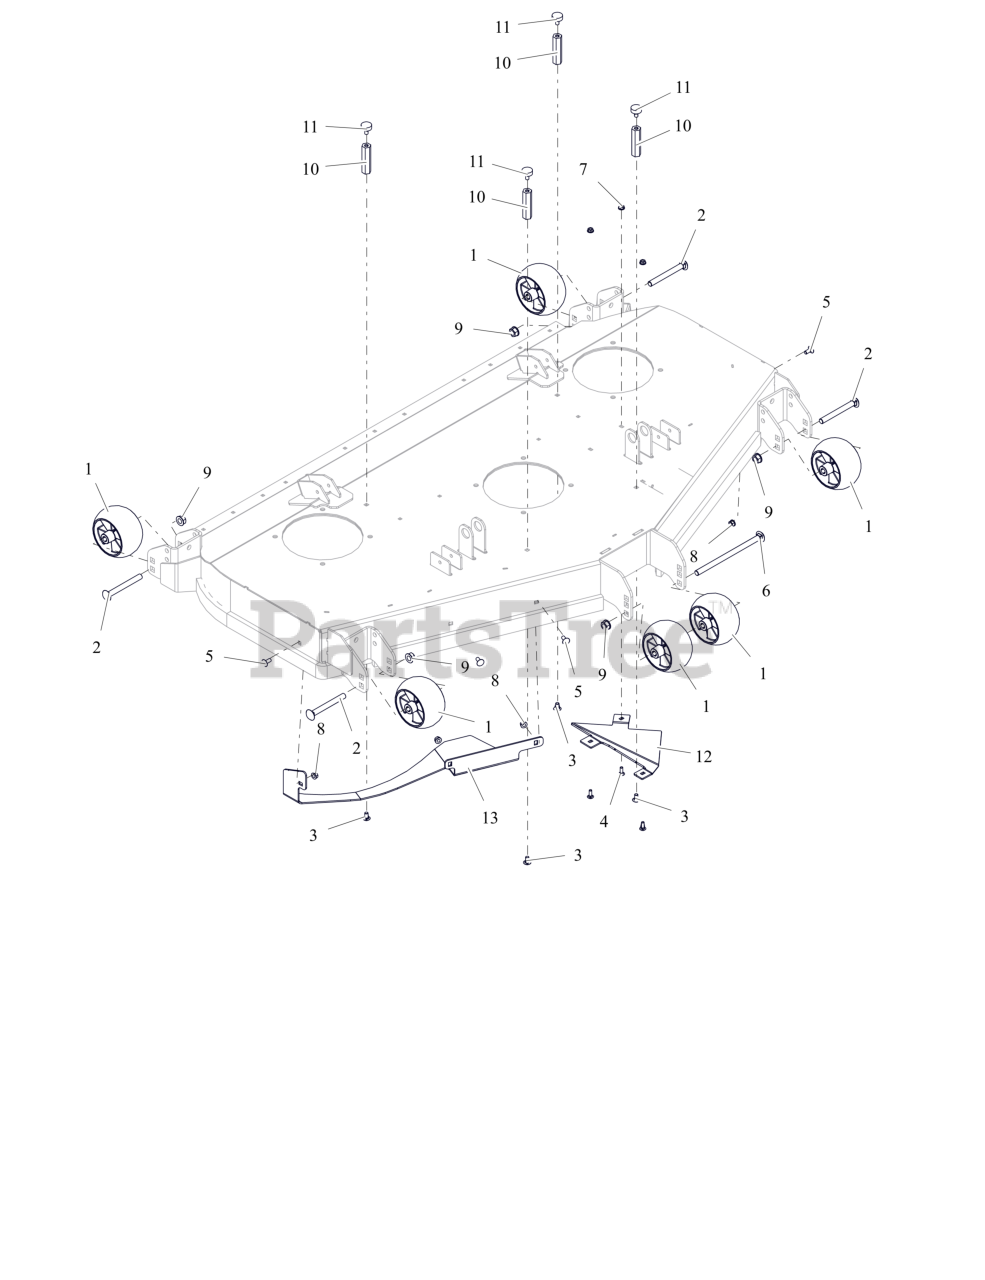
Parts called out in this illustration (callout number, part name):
1	WHEEL, ANTI SCALP - 5X3 CTR W/RIBS
2	BLT,RHSN .50-13X4.50 G5 ZCC
3	BTL,RHSSN .313-18 X 0.625 G5 ZCC
4	BLT, RHSN .25-20X.750 G5 ZCC
5	BLT, RHSSN.31-18X.750 G5 ZCC
6	BTL,RHSN .500-13 X 8.5S G5 ZCC
7	NUT-LK-CTR-FLG .25-20 ZC120
8	NUT,LK-CTR-FLG .31-18 GF ZCC
9	NUT-LK-CTR-FLG .500-13 GG ZCC
10	NUT, COUPLING .31-18 X 3.00
11	BUMPER, RUBBER
12	BAFFLE, INSERT TRIANGLULAR (RED)
13	DEFLECTOR, BAFFLE BOLT-IN (RED)
